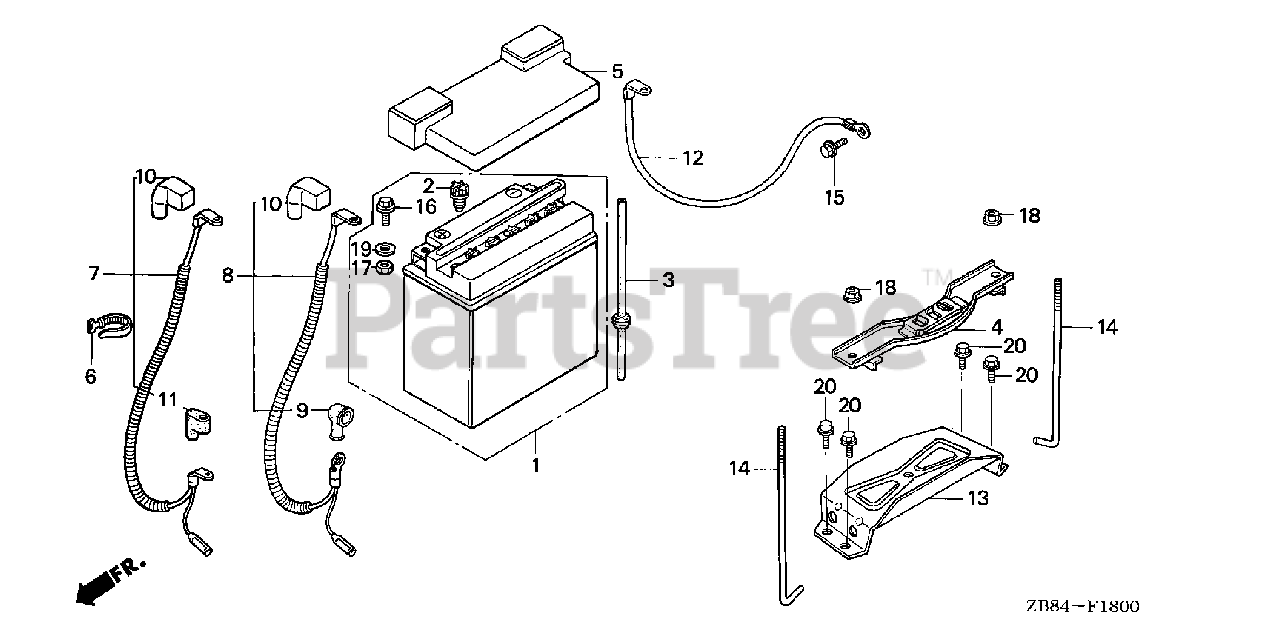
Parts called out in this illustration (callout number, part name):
1	BATTERY (YB18L-A) (YUASA)
1	BATTERY (YB18L-A)
2	PLUG, FILLING
3	TUBE, BATTERY BREATHER
4	PLATE, BATTERY SETTING
5	COVER, BATTERY
6	BAND B1, CABLE
7	CABLE ASSY., STARTER
10	COVER, BATTERY TERMINAL
11	COVER B, MAGNETIC SWITCH
12	CABLE ASSY., GROUND
13	BASE, BATTERY
14	BOLT, BATTERY SETTING
15	BOLT, FLANGE (6X12) (CT200)
16	BOLT, BATTERY TERMINAL
17	NUT, BATTERY TERMINAL
18	NUT, FLANGE (6MM)
19	WASHER, BATTERY TERMINAL
20	BOLT, FLANGE (6X12)
